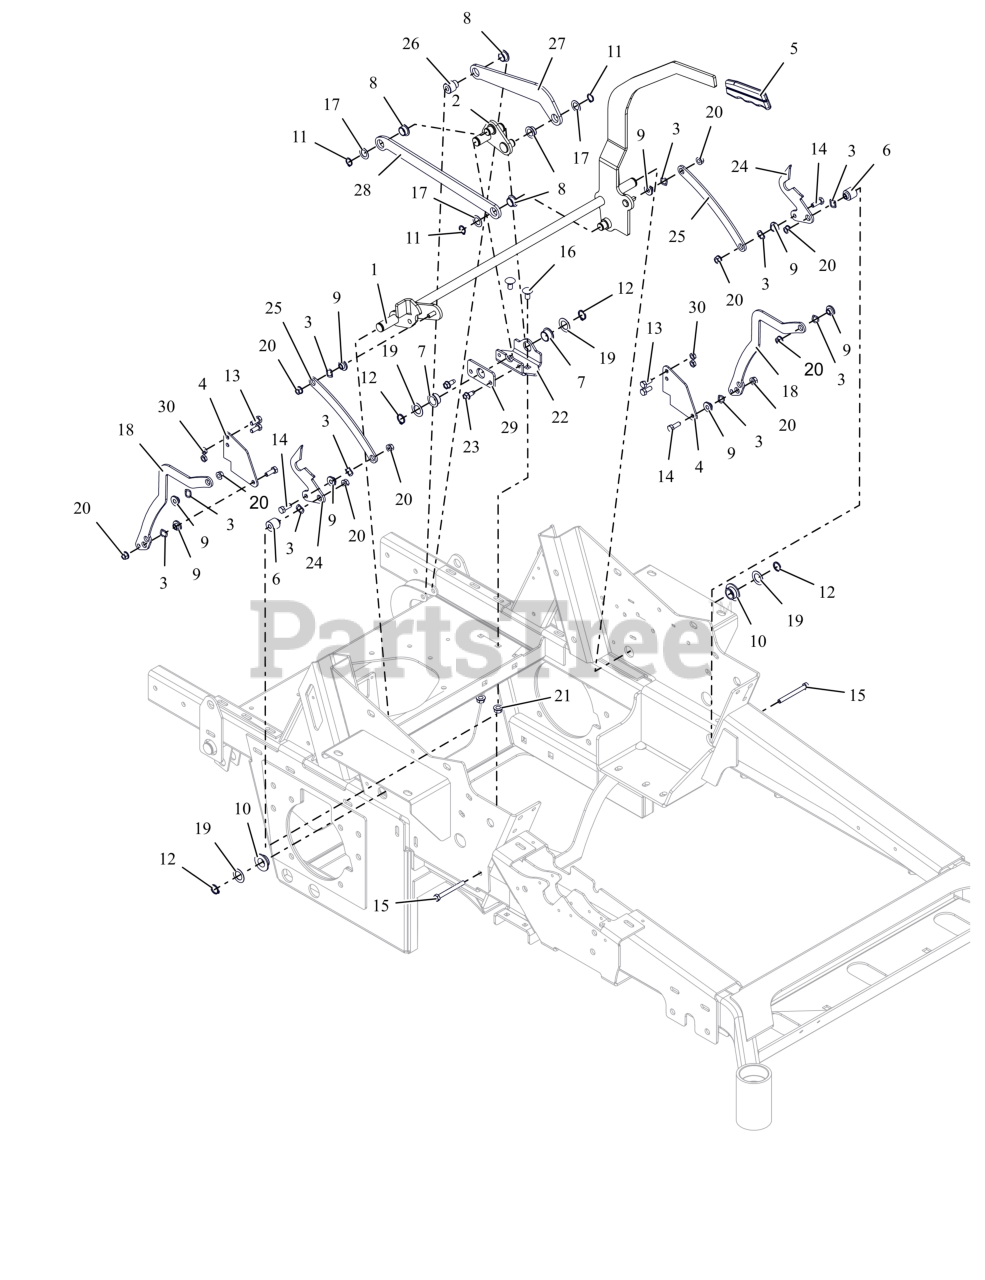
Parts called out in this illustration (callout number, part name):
1	WLDMT, PARKING BRAKE ARM
2	WLDMT, BRAKE ACTIVATION PIVOT
3	WAVE WASHER .531X.781X.125FH
4	BRKT- HTJ SPEED CONTROL -BLACK
5	GRIP, PARKING (GRAY)
6	BUSHING FLANGED - .318X.500X.972X.875
7	BSHG, FLANGE .750 X .875 X .5000 X 1.125
8	BSHG, FLANGE .625 X .750 X .375 X 1.000
9	BSHG-FLG .32X.500X.344X.880
10	BSHG, FLANGED .762 X 1.48 X .44 IGLIDER
11	RG-RTNG-EXT .625X.050
12	RG-RTNG-EXT .689X.078
13	BLT,HEX .31-18X.75 G5 ZCC
14	BLT, HEX .31-18X.875 G5 ZCC
15	BLT, HEX .31-18X3.00 G5 ZCC
16	BLT, RHSN .38-16X.750 G5 ZCC
17	WSHR-THRST .625 X 1.0 X .03
18	LINK- SPEED CONTROL -HTJ (BLK)
19	WSHR-HDND-THRST .758X1.23X.031
20	NUT,LK-CTR-FLG .31-18 GF ZCC
21	NUT-LK-CTR-FLG .375-16 GF ZCC
22	BRKT, BSHG MTG
23	SCR,TAP .312-18X.75 HWH TR ZCC
24	BRKT, BRAKE - RTN (BLACK)
25	BRKT, LINK - BREAK RTN (BLACK)
27	LINK, BRAKE ACTIVATION REAR
28	LINK, BRAKE ACTIVATING FRONT
29	PLATE, BSHG MOUNTING
30	NUT-LK-CTR-JAM .312-18 GB ZCC
